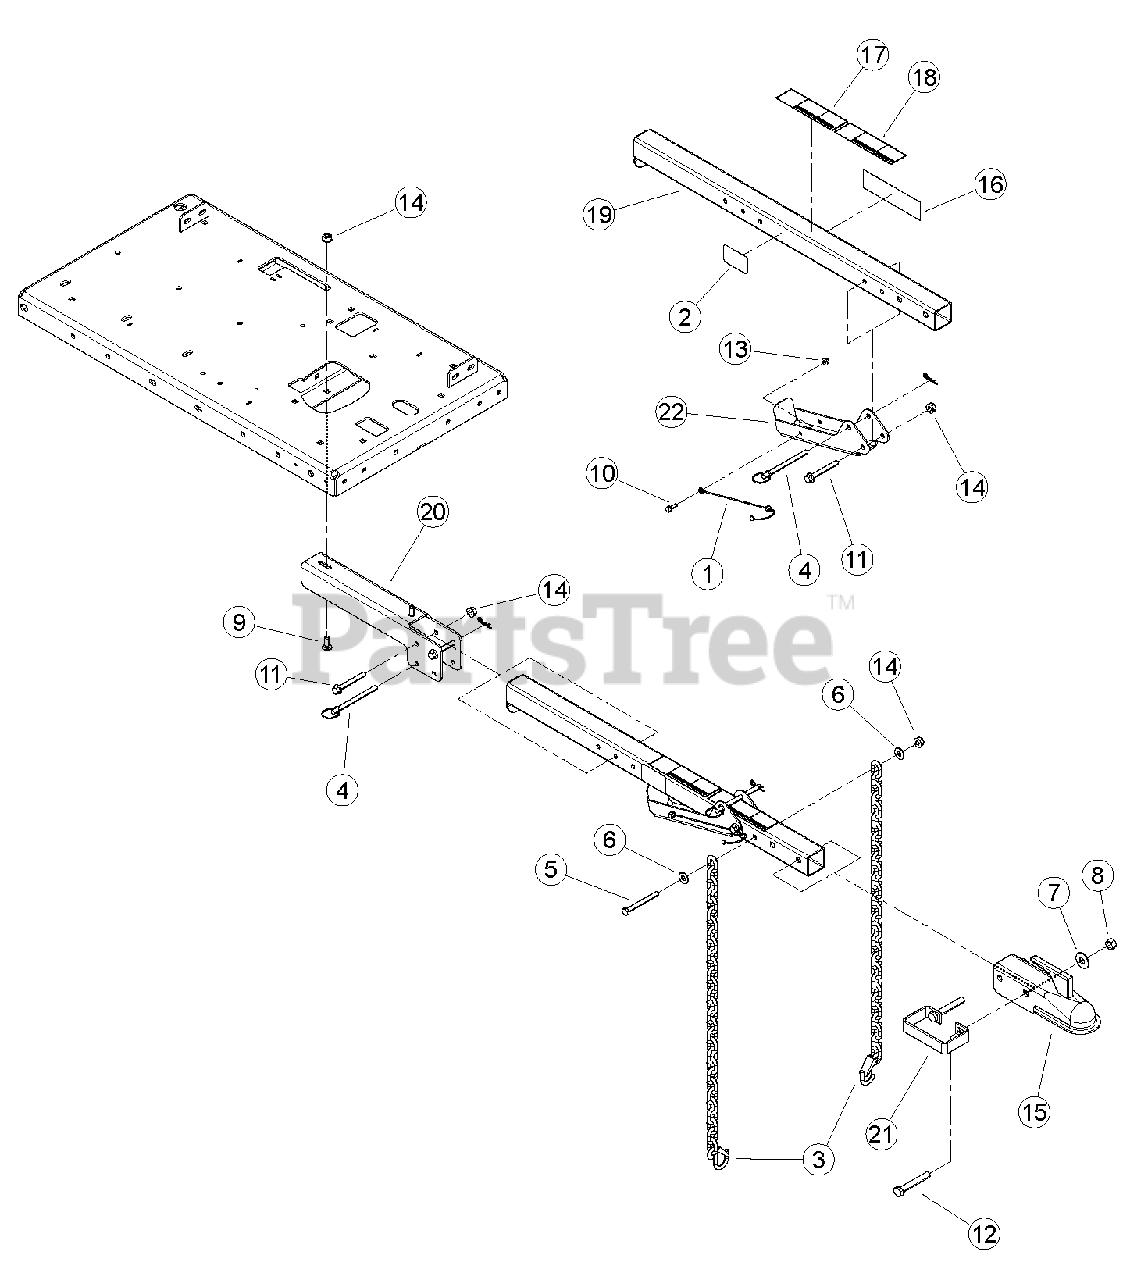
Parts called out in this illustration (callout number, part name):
1	LANYARD, NYLON
2	REFLECTOR, WIDE ANGLE AMBER
3	CHAIN, SAFETY 5000 LB W/ LATCH
4	PIN, 3/8 HITCH
5	BOLT, 3/8 X 3-1/2" HEX HD GR5 ZP
6	WASHER, 3/8" FLAT ZP
7	WASHER, 1/2" FLAT ZP
8	NUT, 1/2" CENTERLOCK GRB ZP
9	BOLT, 3/8 X 1" CRG GR5 NC ZP
10	BOLT, 1/4-20 X 3/4 HWH GR5 CZP
11	BOLT, 3/8 X 3 FLANGE NC
12	BOLT, 1/2 X 3 1/4 HCS GR5 ZP
13	NUT, 1/4-20 NYLOCK FLANGE
14	NUT, 3/8-16 NYLOCK FLANGE
15	TRAILER HITCH COUPLER
16	DECAL, SAFETY CHAINS
17	DECAL, TRAILER ELECTRICAL
18	DECAL, SAFE COUPLING
19	WELDMENT, HITCH POLE
20	CHANNEL, HITCH POLE
21	HANDLE, COUPLER
22	STAND, JACK
